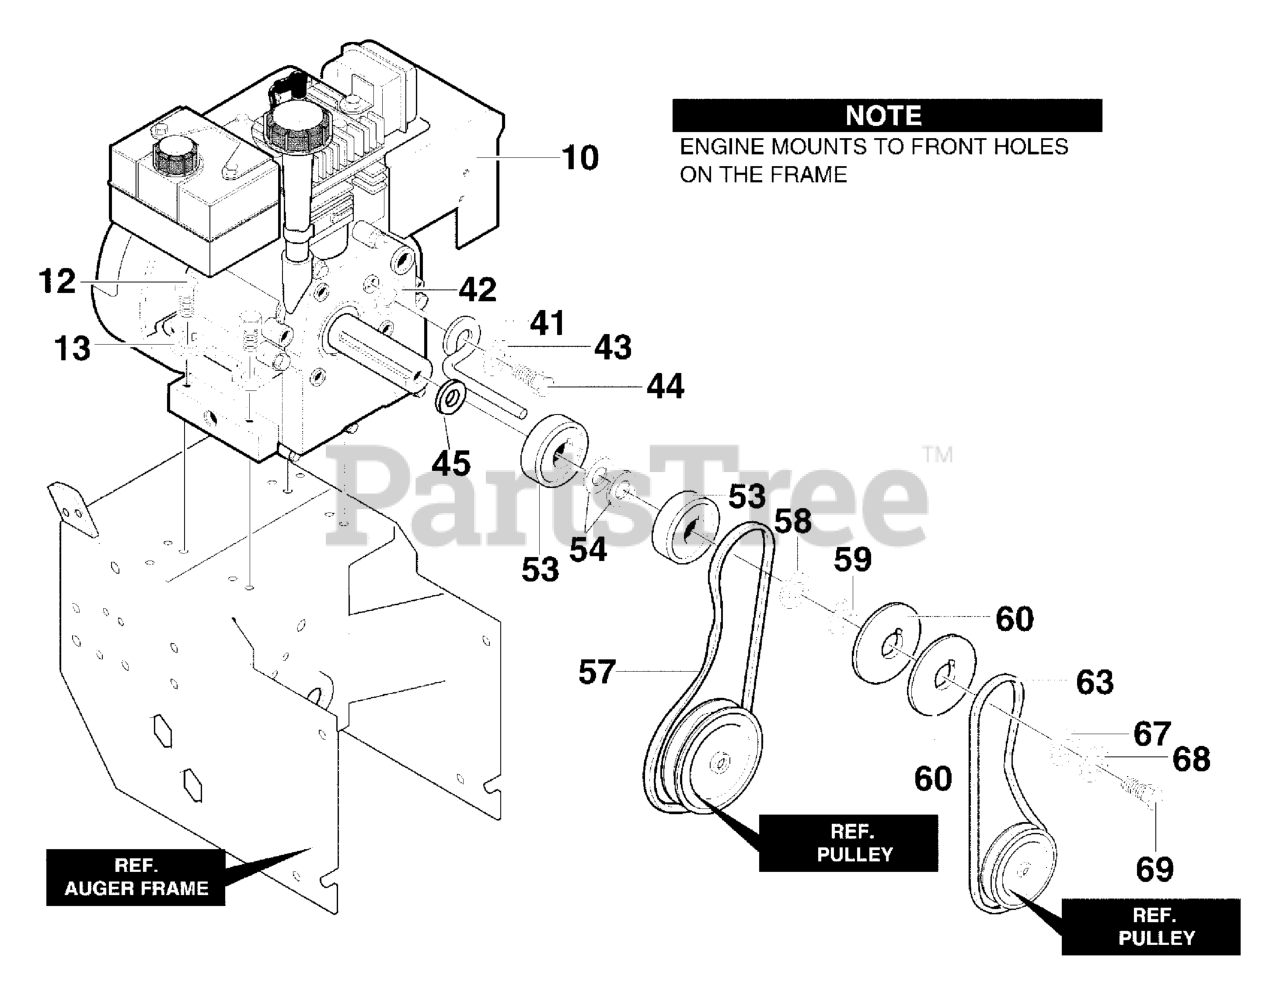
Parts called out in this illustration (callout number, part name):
10	ENGINE
12	SCREW, 5/16-18
13	WASHER
41	GUIDE, ROD BELT
42	PLASTIC WASHER
43	WASHER
44	SCREW, 5/16-24 x 1.00
53	PULLEY, HALF
54	WASHER, FLAT
57	BELT, V 3L 33.13LG
58	FLATWASHER
59	SPACER, SLEEVE
60	PULLEY, ENGINE
63	BELT, V 4L38.1LG
67	WASHER, FLAT
68	WASHER,HVSPTLK .38ID
69	SCREW, 3/8-24 x 1.00
